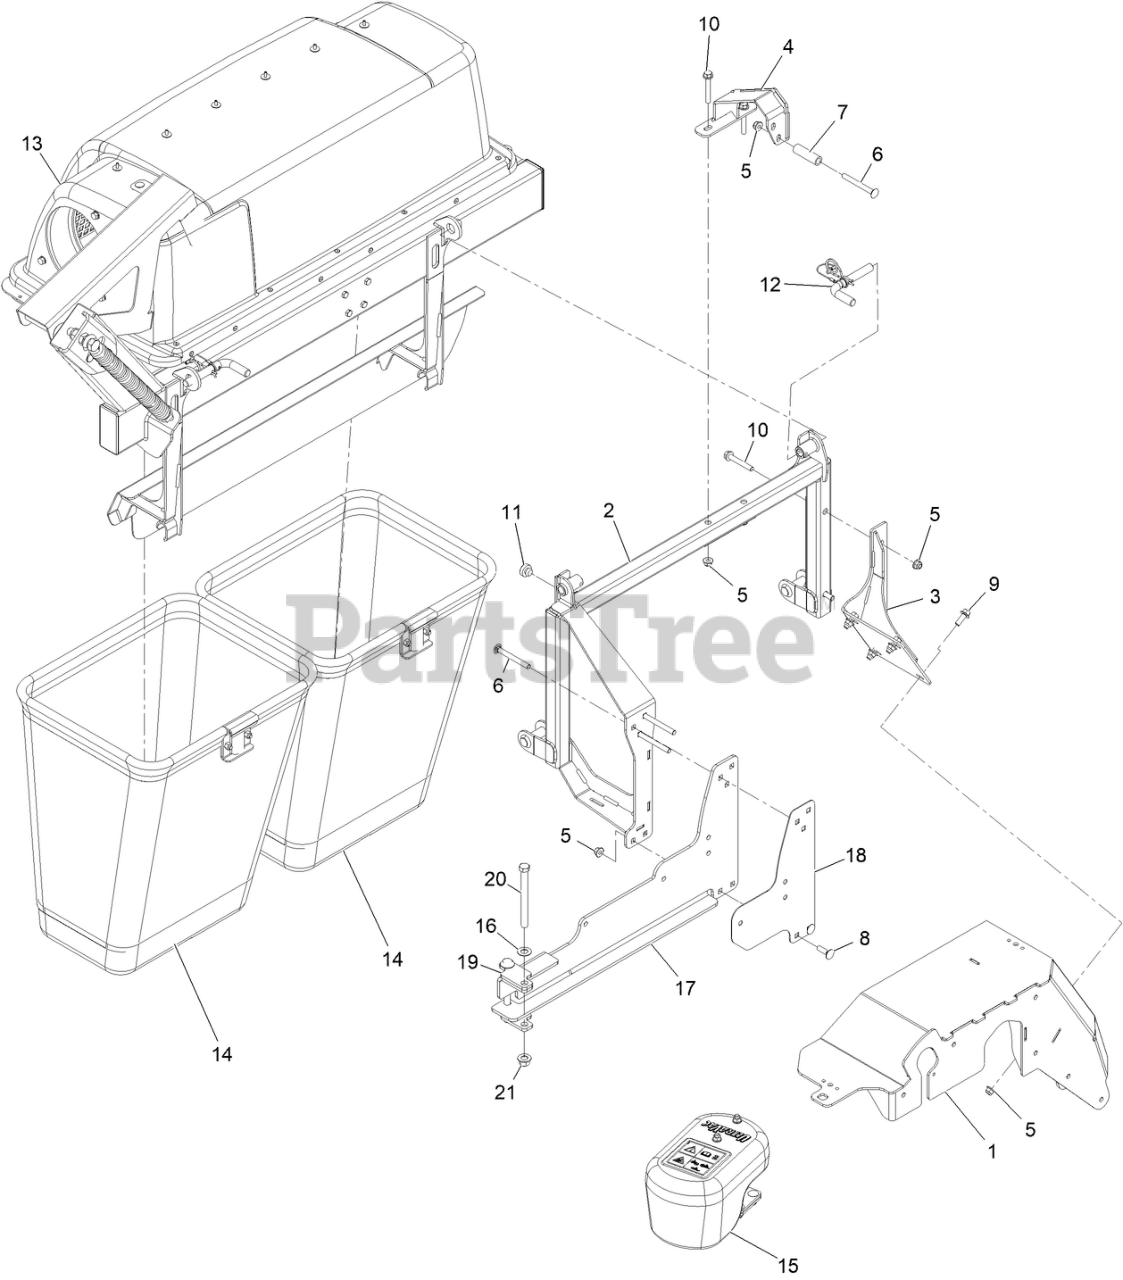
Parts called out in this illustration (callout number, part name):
1	FENDER-RH,BAGGER
2	FRAME-MOUNT, BAGGER
3	SUPPORT-REAR, BAGGER
4	SUPPORT-TOP
5	NUT-HF, NI
6	SCREW-CARR
8	BOLT-CARR
9	SCREW-HHF 3/8-16 X 1
10	Screw-HHF
12	PIN-MOUNT, BAGGER
13	Hood ASM-Bagger
14	BAG AND FRAME ASM
15	ASM-CASTER WEIGHT
17	Plate-Side-Frame
18	PLATE-SHIM-FRAME
19	SUPPORT-TOP-FRAME
20	SCREW-HH
21	Nut-Lock 1/2-13
